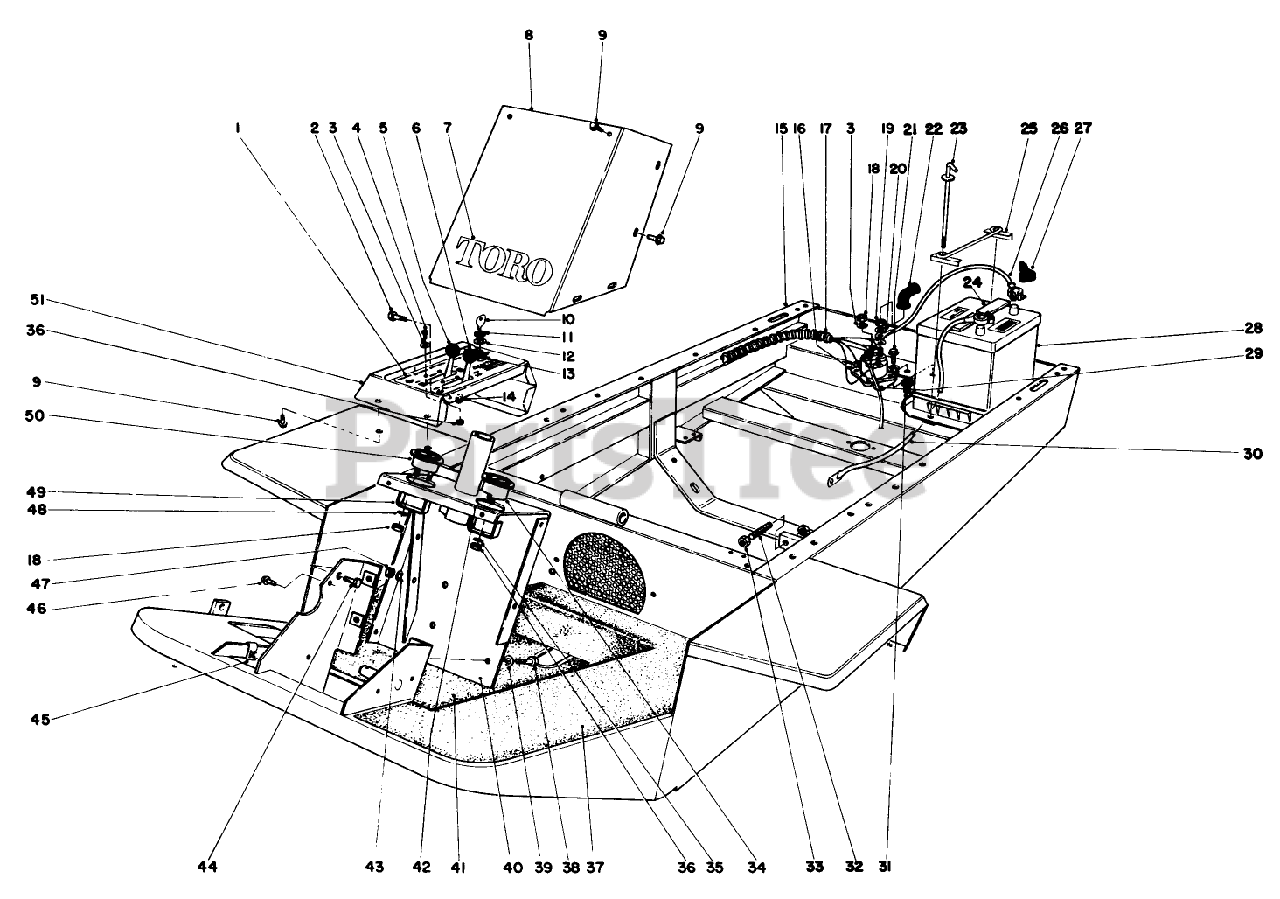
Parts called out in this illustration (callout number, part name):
1	Decal-Instrument Panel
2	SCREW-HH
3	WASHER-LOCK
4	10-24 X 5/8 PAN HD MS
5	CHOKE CONTROL
6	THROTTLE CONTROL
7	DECAL
8	Tower Cover
9	SCREW-THD FRM,HWH
10	Key
11	NUT-HH
12	WASHER-TOOTH, INTERNAL
13	SWITCH-STARTER
14	WASHER-FLAT
15	Frame
16	SOLENOID
17	WIRE HARNESS
18	NUT-HEX
19	NUT-JAM, BRASS
20	WASHER-LOCK
21	SCREW-HH
22	BATTERY BOOT
23	BATTERY BOLT WA B
24	PUSH-ON BATTERY CAP
25	BATTERY HOLD DOWN WA
26	BATT/SOLENOID WIRE
27	BOOT-CABLE, BATTERY
28	Battery
29	SOLENOID TO START WIR
30	BATTERY GROUND WIRE
31	NUT-INSERT
32	STOP PIN PP
33	NUT-JAM
34	HOUR METER
35	WASHER-LOCK, INT
36	NUT-HEX
37	NON SKID (TUNNEL)
38	SCREW-HH
39	WASHER-LOCK
40	Steering Post
41	NON-SKID-FLOOR
42	INSTRUCTION DECAL
43	WASHER-LOCK
44	SCREW-HH
45	SPEED NUT
46	SCREW-HWH
47	NUT-HEX
48	WASHER-FLAT
49	MTG CLAMP F/W GUAGE
50	AMMETER GAUGE ASSY
51	Instrument Panel
